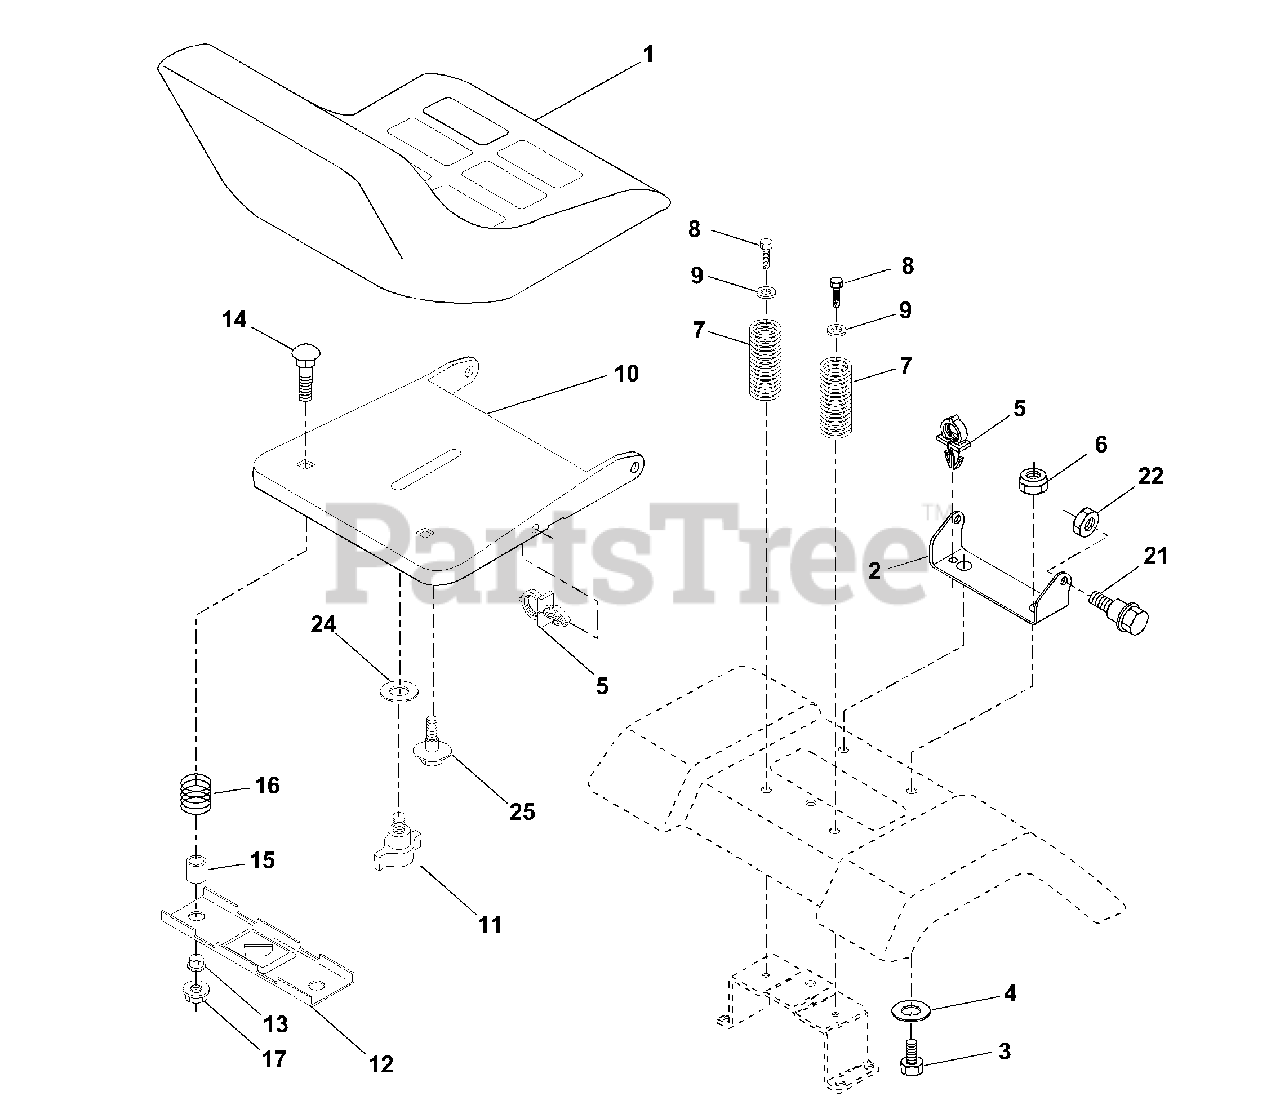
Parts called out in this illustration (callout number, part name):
1	Seat
2	Bracket Pnt Pivot Seat (blk )
3	Bolt
4	Washer 13/32 x 1 x 10 Ga
5	Clip Push-In Hinged
6	Nut
7	Spring Seat Cprsn 2 250 Blk Zi
8	Screw 3/8-16 x 1.5
9	Washer 13/32 x 1 x 14 Ga
10	Pan Pnt Seat (blk )
11	Knob Seat Adj Wingnut
12	Bracket Pnt Mounting Switch
13	Bushing Snap Blk Nyl 50 Id
14	Bolt Rdhd Sht Nk 1/4-20 x 1-1/2
15	Spacer Split 28 x 96 Yel Zinc
16	Spring Cprsn 1 27 Blk Pnt
17	Nut Lock 1/4 Lge Flg Gr 5 Zinc
21	Bolt Shoulder 5/16-18 Unc Blkz-2A
22	Nut
24	Washer 17/32 x 1-3/16 x 12 Ga
25	Bolt Shoulder 5/16-18 x 62
